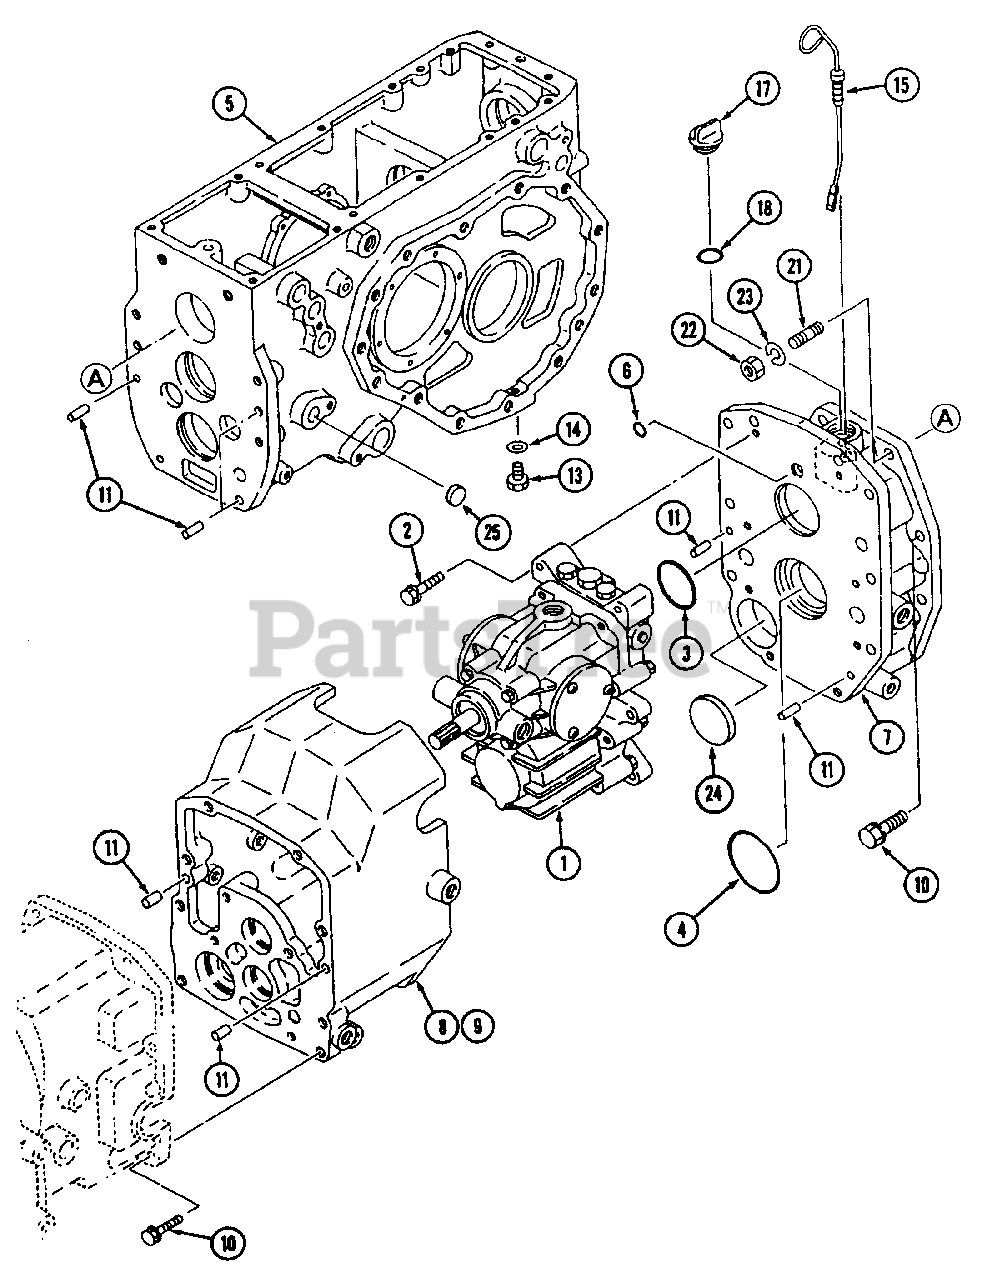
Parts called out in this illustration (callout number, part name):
1	Hydrostatic Unit
8	Case, HST
14	Seal, Washer
